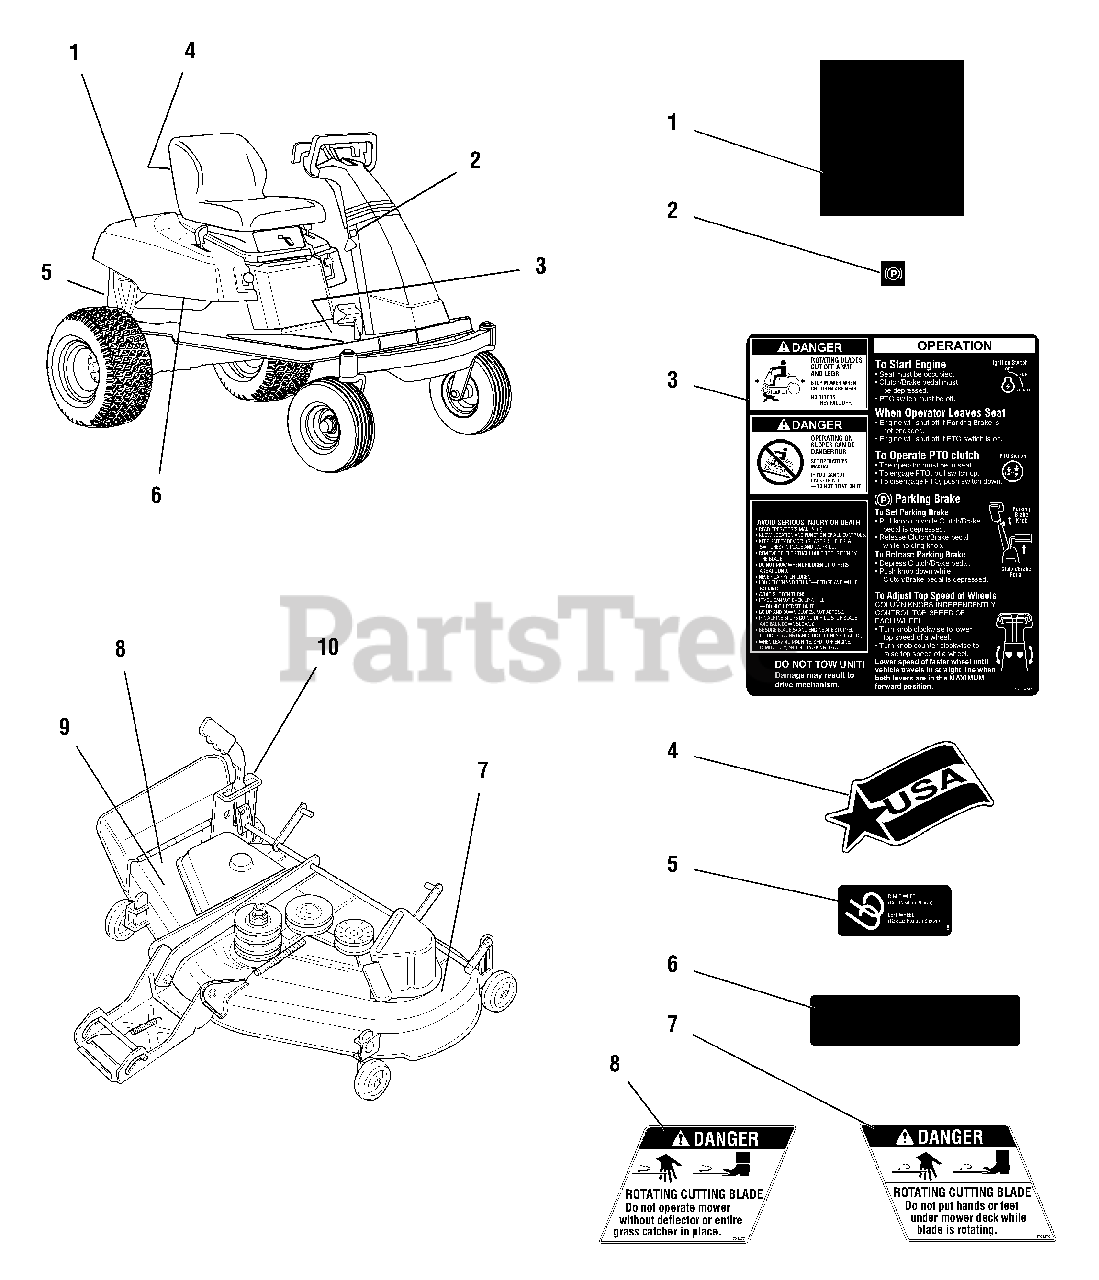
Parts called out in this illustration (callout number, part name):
1	DECAL, Belt/Blade (under Seat Deck)
2	DECAL, Parking Brake
3	DECAL, Operating Instructions
4	DECAL, Logo, USA
5	DECAL, Transmission Release
6	DECAL, Oil Reservoir
7	DECAL, Danger, Rotating Cutting Blade
8	DECAL, Danger, Chute in Place
9	DECAL, Cutting Width, 38"
9	DECAL, Cutting Width, 44"
10	DECAL, Height of Cut
11	DECAL, OPEI
12	PLATE, Manufacturing No/Serial No
13	DECAL, Decibel, Export Only
14	DECAL, CE, Export Only
